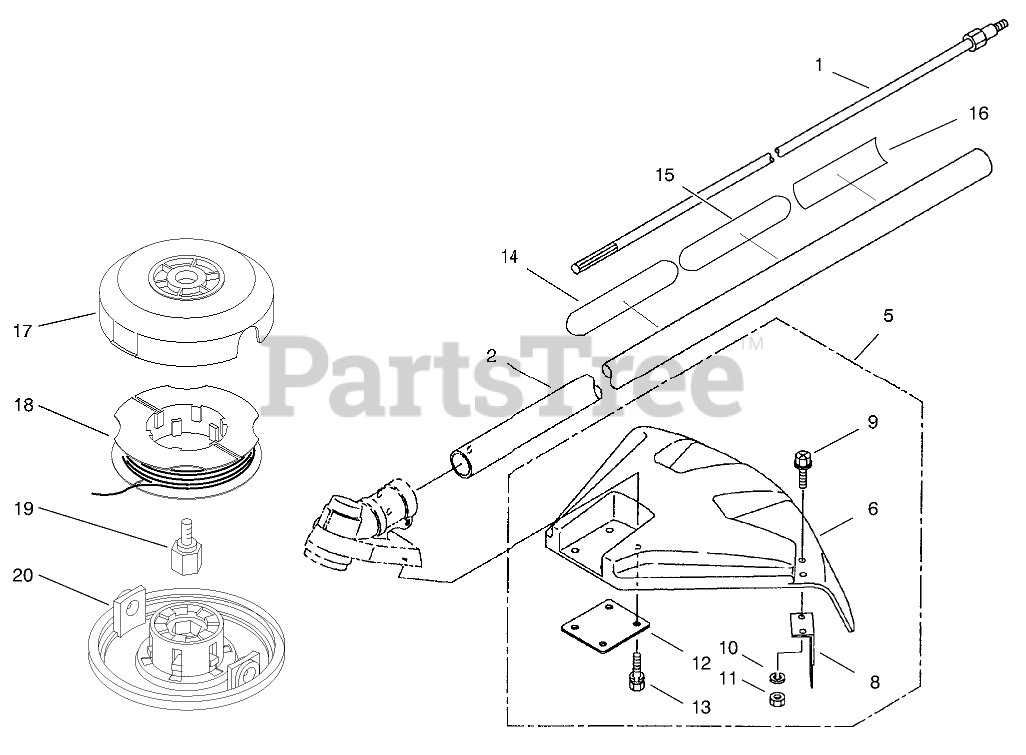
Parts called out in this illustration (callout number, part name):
1	ASM - DRIVESHAFT
2	Driveshaft Tube Assembly (Incl. Ref. # 14, 15)
5	Safety Cover Assembly (Incl. Ref. # 6-13)
6	COVER - SATETY
8	CUTTER - STRING
10	WASHER - SPRING
11	NUT M5
12	PLATE
14	DECAL - CAUTION
15	DECAL - CAUTION
16	DECAL - TORO
18	SPOL W/ LINE
19	MOUNTING STUD
20	INDEXING BASE
